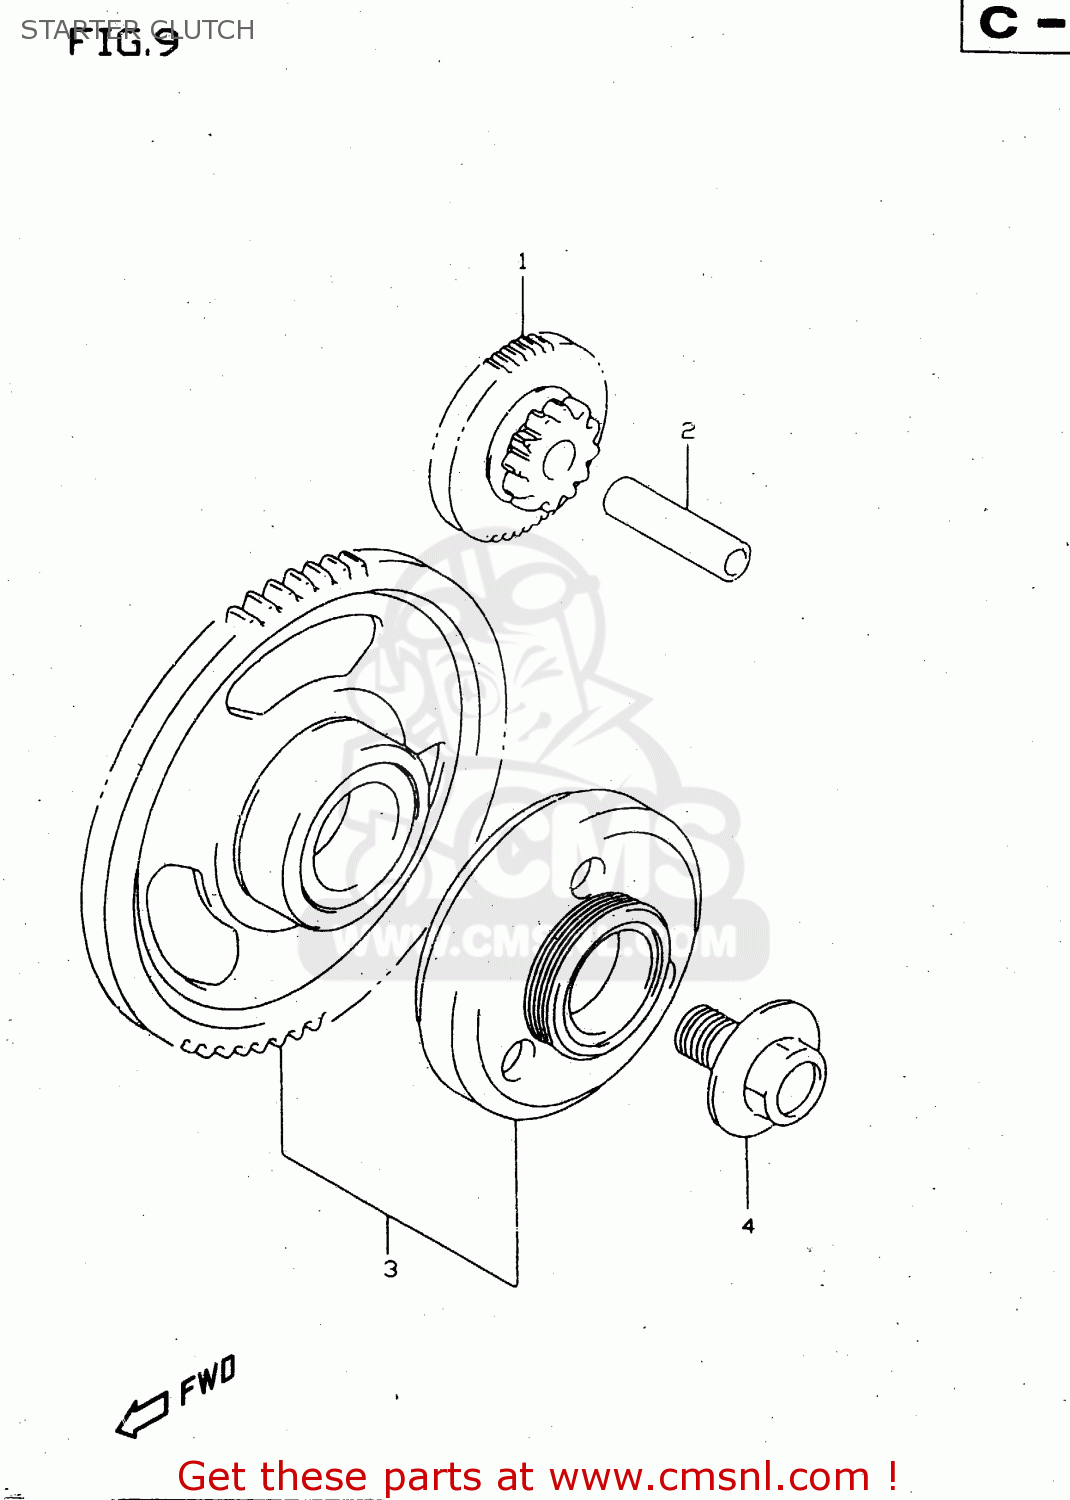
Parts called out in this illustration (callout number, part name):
1	GEAR,STARTER IDLE(NT:12,53)
2	PIN(7X11X42)
3	CLUTCH SET,STARTER
4	BOLT(14X21)
